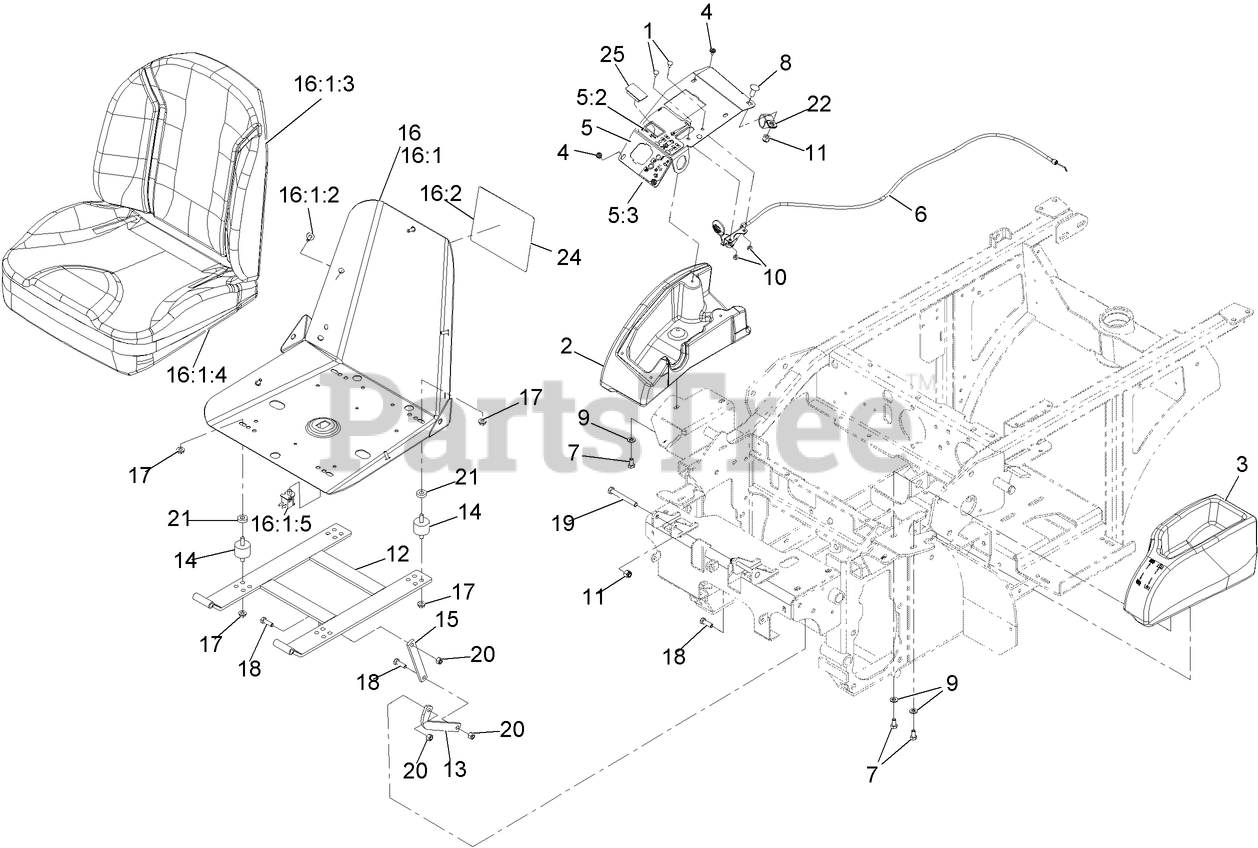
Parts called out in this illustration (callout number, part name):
1	BOLT-CARR
2	CONSOLE-RH
3	CONSOLE, LH GREY
4	SCREW-PPH
5	CONTROL PANEL ASM
5:2	Decal-Console
5:3	DECAL-SPEED CONTROL
6	CABLE-THROTTLE
7	SCREW-HH
8	SCREW-CARR
9	WASHER-PLAIN
10	NUT-LOCK, NI
11	NUT-LOCK, NI
12	FRAME-SEAT
13	LINK-SEAT STOP
14	MOUNT-VIBRATION, RUBBER
15	LINK-SEAT
16	ASM-SEAT W/DECAL
16:1	ASM-SEAT, NAVIGATOR
16:1:2	BOLT-SEAT
16:1:3	CUSHION-SEAT, BACK
16:1:4	COVER-SEAT BOTTOM SVC
16:1:5	SWITCH-BAIL
16:2	Decal-Service Aid
18	SCREW-HH
19	SCREW-HH
20	NUT-LOCK, NI
21	SPACER
22	CLIP-LOOM
24	Decal-Service Aid
25	PLUG-HOLE
